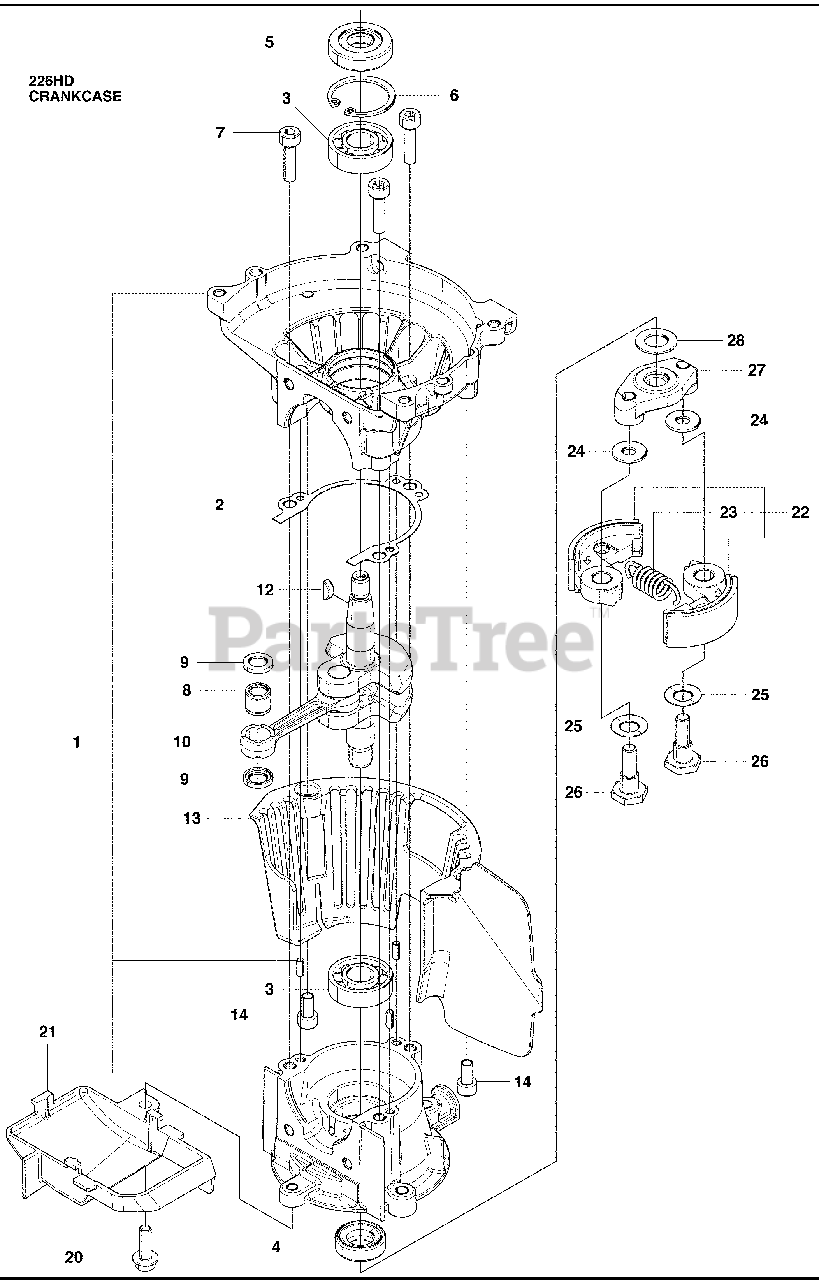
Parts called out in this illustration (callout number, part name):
1	CRANKCASE COMP
2	Case Gasket
3	Bearing
4	Seal
7	Torx Bolt
10	Crankshaft, Comp
14	BOLT TORX M5XL10 T27
20	Bolt
21	Engine Cover
22	Shoe, Comp
27	Clutch Plate
